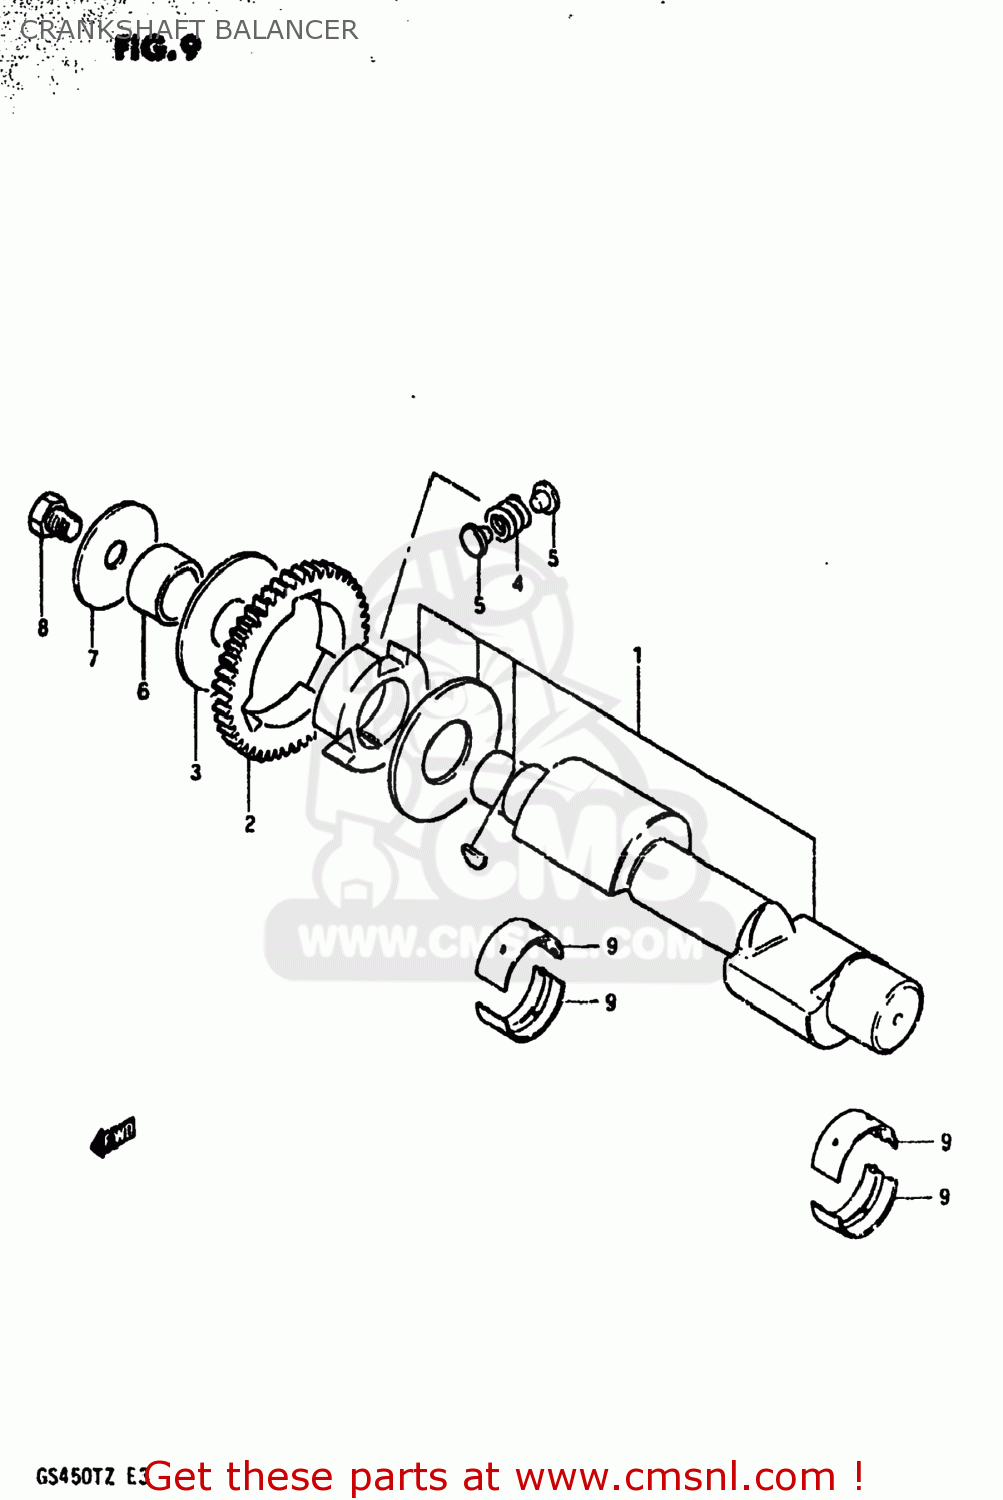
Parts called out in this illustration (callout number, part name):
1	BALANCER,CRANKSHAFT
2	GEAR,CRANK BALANCER DRIVE
3	WASHER
4	SPRING
5	PIN
6	SPACER
7	WASHER(12X50X3)
8	BOLT
9	METAL CRANKSHAFT
